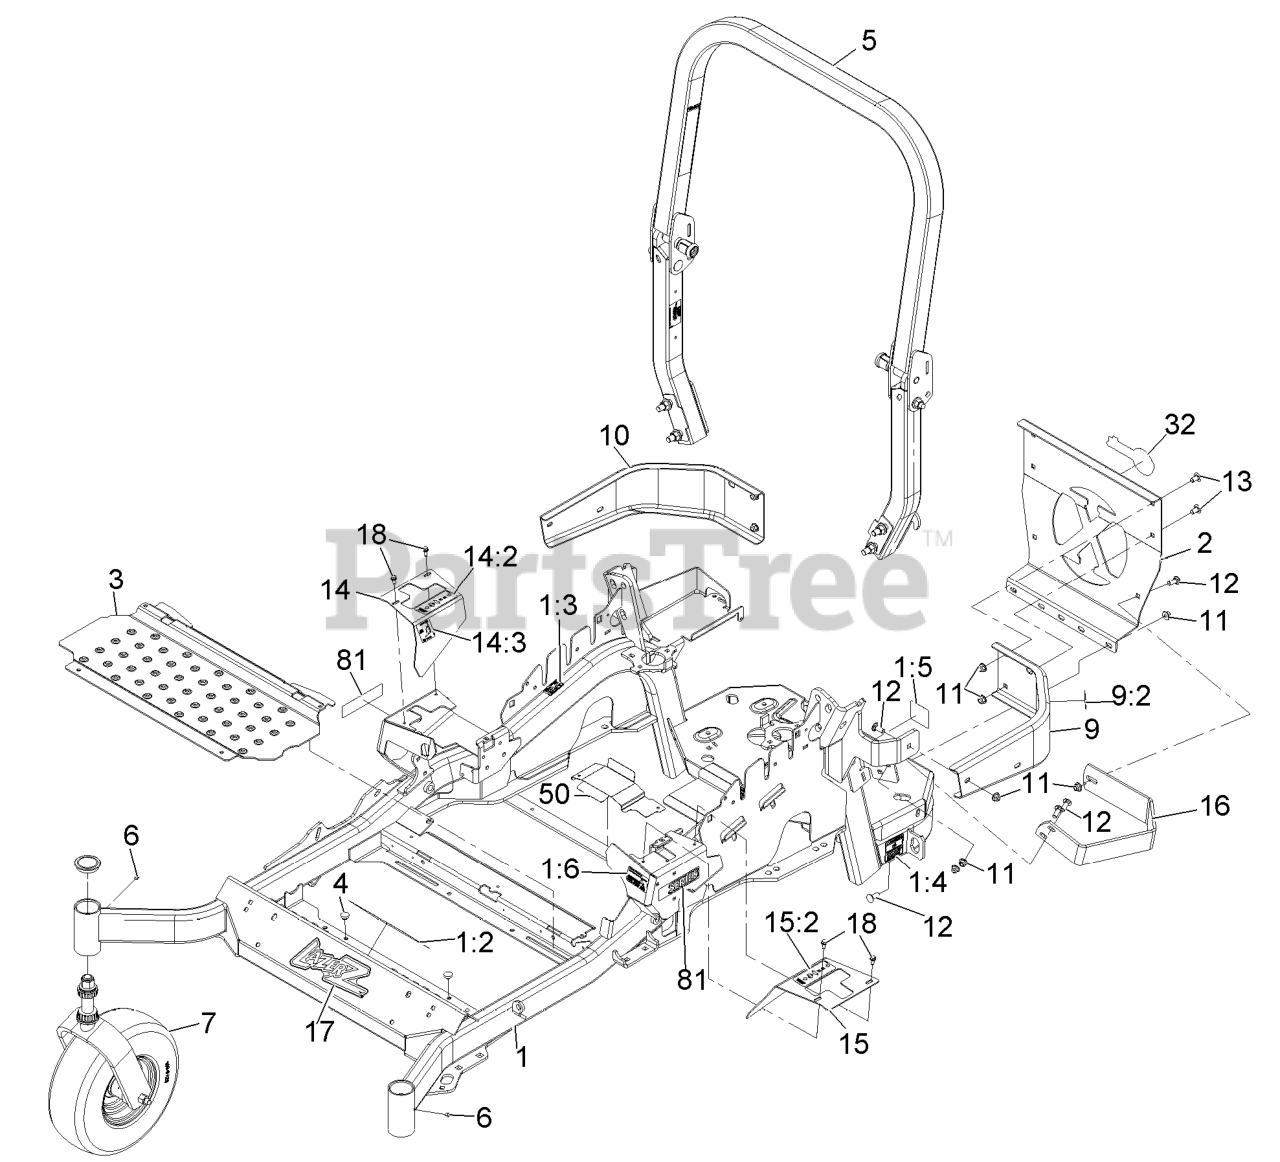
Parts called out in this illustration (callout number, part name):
1	MAIN FRAME ASM
1:2	DECAL-SLOPE
1:3	DECAL-CAUTION
1:4	DECAL-BELT DRIVE
1:5	DECAL-SPARK ARRESTER
1:6	DECAL-FUEL FILL
2	PLATE,REAR GUARD
5	ROPS ASM
7	Asm,Front Caster W/Fork
9	LH BUMPER ASM
9:2	DECAL-CAUTION
10	BUMPER-RH
11	NUT-HF, NI
12	SCREW-CARR
13	SCREW-CARR
14:2	DECAL-MOTION CONTROL
15	LH MOTION CONTROL COVER ASM
15:2	DECAL-MOTION CONTROL
17	DECAL,LAZER MODEL
18	SCREW-HWH
50	GUARD-BELT
81	DECAL-E-SERIES
